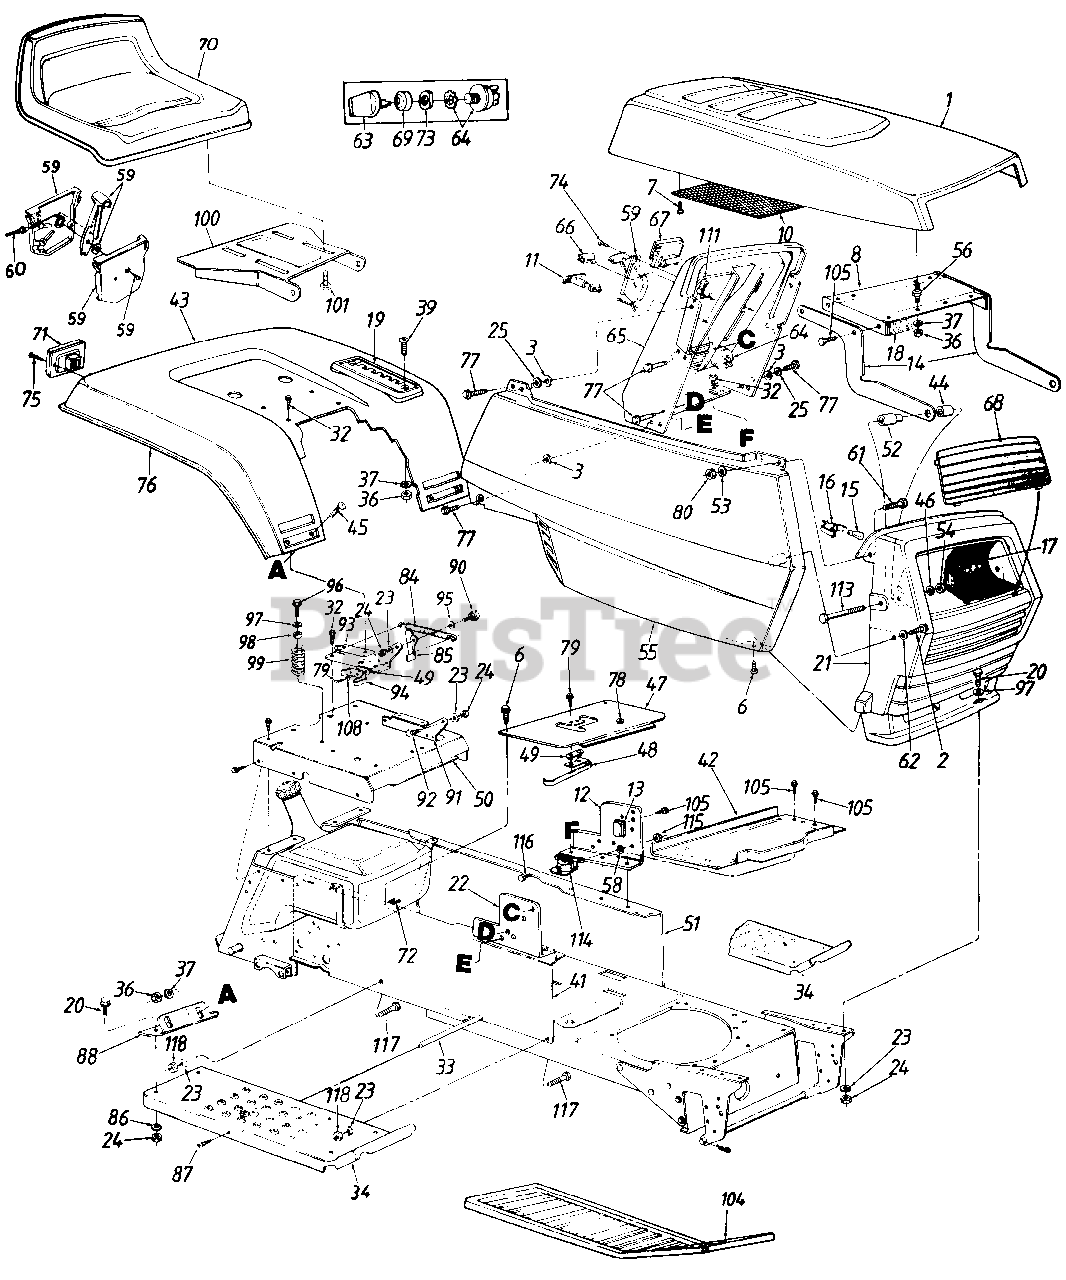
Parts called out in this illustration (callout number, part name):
3	8O1t Retainer 1/4 I.D.
6	Truss Mach. B-Tap Scr. #10 x .5" Lg.
7	Hex Wash Hd. AB-Tap Scr. #8 x .5" Lg.
8	Hood Plate
11	Choke Control
12	Dash Support Brkt.-L.H.
13	Circuit Breaker
14	Hood Hinge
15	Lamp
16	Twist Lock-Lamp Socket
17	Retlector-Headlight
19	Speed Control Index Brkt.
20	Hex Bolt 5/16-18 x .75" Lg.
21	Grille
22	Dash Support Bracket-R.H.
23	L-Wash. 5/16" I.D.'
24	Hex Nut 5/16-18 Thd.
25	Fl-Wash. 1/4" I.D. x .93" O.D.
32	Hex Wash. Hd. AB-Tap Scr. 5/16 x .75' Lg.
33	Running Board Rod
37	L-Wash. 1/4" I.D.
39	Truss Mach. Scr. 1/4-20 x .62"
41	R.H. Side Frame
42	Battery Carrier
45	Carriage Bolt 1/4-20 x .50" Lg.
46	Fl-Wash. .328" I.D. x .68" O.D.
47	Transmission Panel
48	Reverse Safety Switch
49	Insulator Nut Plate
50	Seat Plate
51	L.H. Side Frame
52	Shld. Spacer .33" I.D.
53	Fl-Wash. .281" I.D. x .5" O.D.
54	Hex Cent. L-Nut 5/16-18 Thd.
55	Side Cover-R.H.
56	Double Ended Stud 1/4-20 Thd.
58	Ext. L-Wash. 1/4" I.D.
59	Throttle Control Box Ass'y.
60	Throttle Control Wire 35" Lg.
61	Hex Bolt 1/4-20 x .62" Lg.
62	Fl-Wash. .281" I.D. x .73" O.D.
64	Ignition Switch
66	Light Switch
67	Ammeter
68	Lens
69	Ignition Switch Cap
71	Taillight Ass'y.
72	Speed Nut #10Z
73	Ignition Switch Nut
74	Truss Mach. AB-Tap Scr. #10 x .5" Lg.
75	Truss Hd. AB-Tap Scr. #6 x .62" Lg.
76	Trim Strip-81"
77	Hex Wash. Hd. Tap Scr. 1/4 x .75" Lg.
78	Snap Bushing
79	Hex Wash. Hd. AB-Tap Scr. #8 x .50" Lg.
80	Hex L-Nut 1/4-20 Thd.
84	Ext. Spring 5.31" Lg.
85	Seat Lift Brkt.
86	Bell-Wash. .345" I.D. x .88" O.D.
87	Rib Neck Bolt 5/16-18 x .75"
91	Seat Pivot Brkt. Support-L.H.
92	Shld. Bolt .437" Dia. x .162"
93	Seat Pivot Brkt. Support-R.H.
94	Spring Switch
95	Spr.-Wash..445" I.D.
96	Hex Wash. Hd. Tap Scr. 5/16-18 x 1" Lg.
97	Fl-Wash. .344" I.D.
99	Compression Spring
100	Seat Pivot Bracket
101	Hex Tap Scr. 3/8-16 x .75"
105	Hex Tap Scr. 1/4-20 x .5" Lg.
108	Fiber Washer
111	Speed Nut 1/4-20 Thd.
113	Hex Bolt 5/16-18 x 2.75"
114	Solenoid
115	Hex Sems Nut 1/4-20 Thd.
116	Hex Bolt 1/4-20 x .5" Lg.
117	Rib Neck Bolt 5/16-24 x .75" Lg.
118	Hex Nut 5/16-24 Thd.
